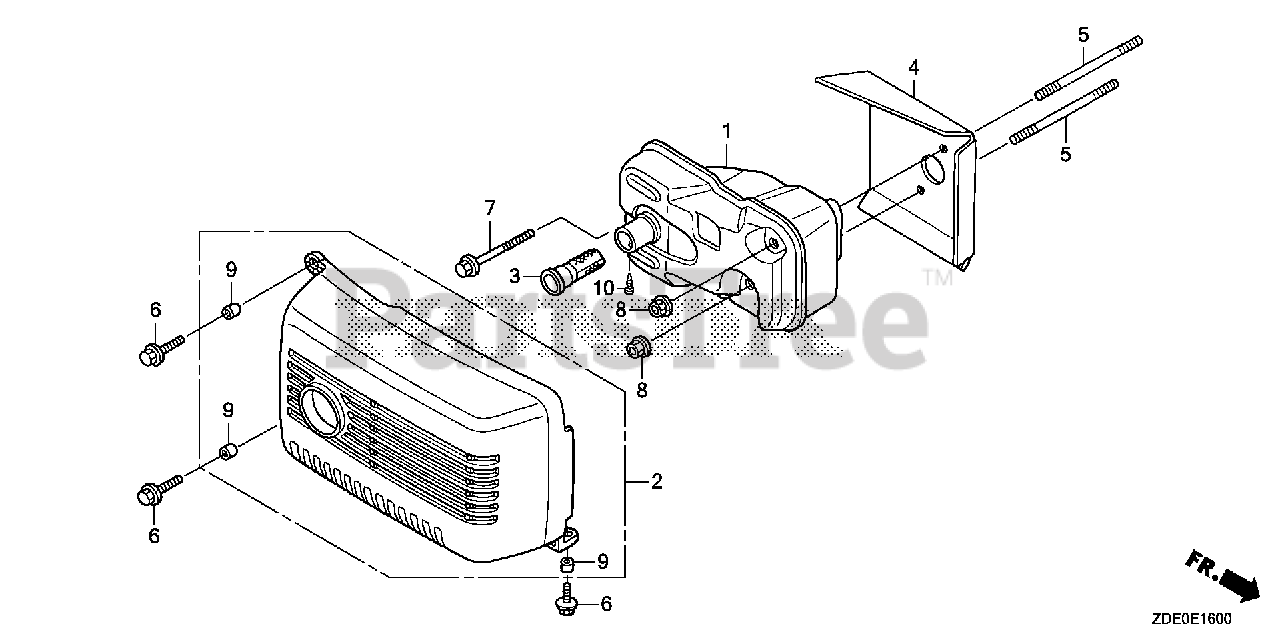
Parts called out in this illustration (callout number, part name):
1	MUFFLER
2	PROTECTOR, MUFFLER
3	ARRESTER, SPARK
4	GUIDE, AIR
5	BOLT 2, STUD (5X55)
6	BOLT, FLANGE (5X16)
7	BOLT, FLANGE (5X35)
8	NUT, SELF-LOCK (5MM)
9	COLLAR, TOP COVER
10	SCREW, TAPPING (4X8)
